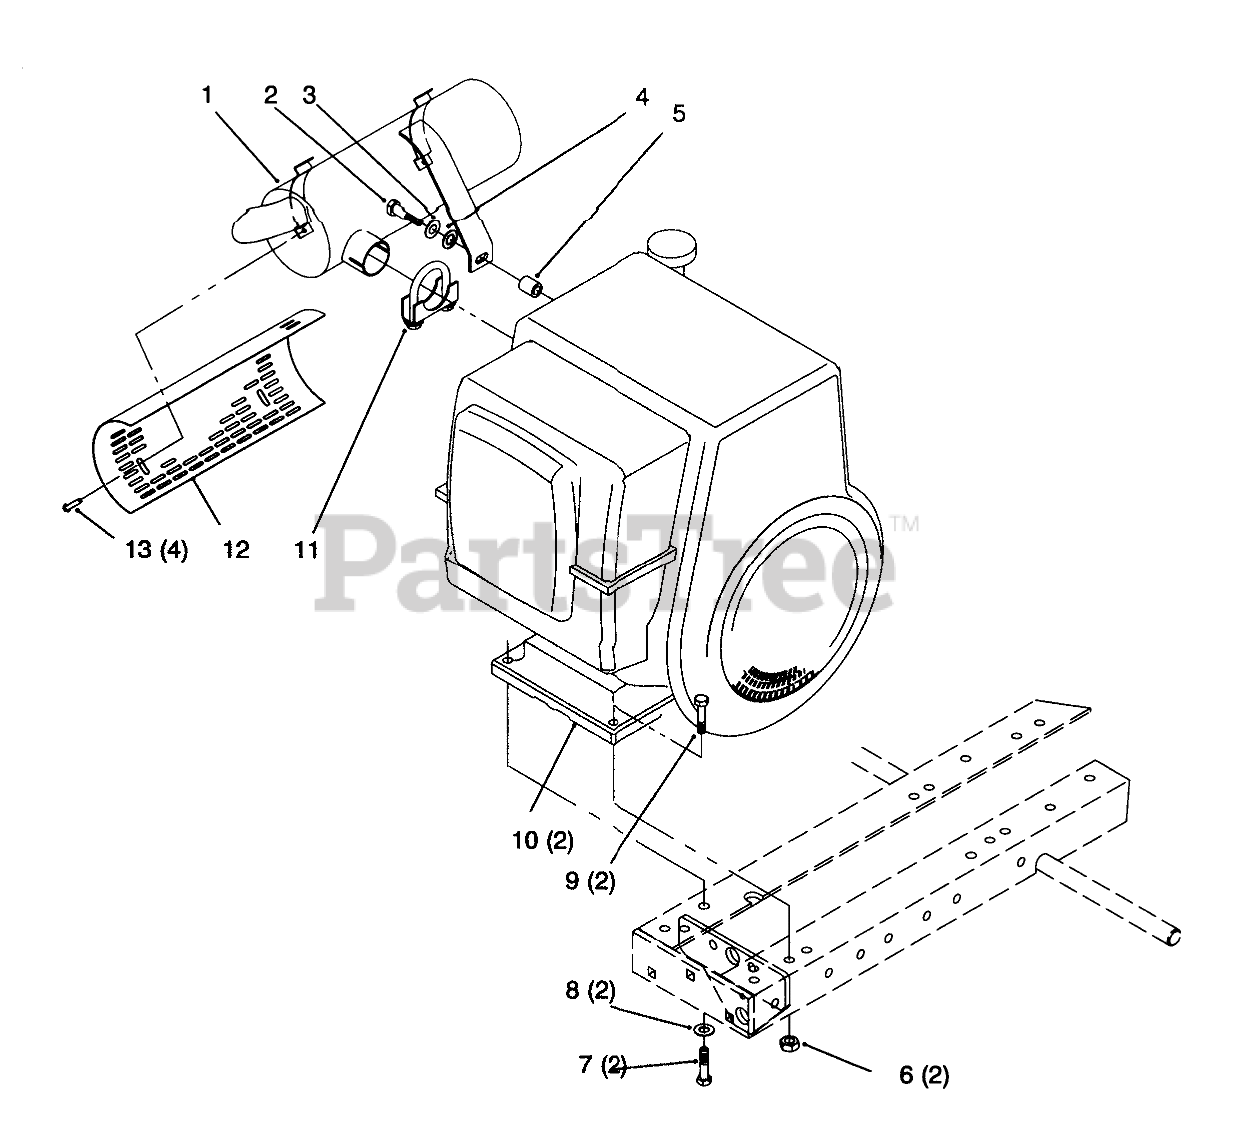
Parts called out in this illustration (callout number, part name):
1	MUFFLER
2	SCREW-HH
3	WASHER-LOCK
4	WASHER-PLAIN
5	SPACER
6	NUT-LOCK, NI
7	SCREW-HH
8	WASHER-LOCK
9	SCREW-HH
10	Engine-12 Hp Kohler
11	CLAMP-1 1/2
12	SHIELD-HEAT
13	SCREW
14	WIRE GROUND
